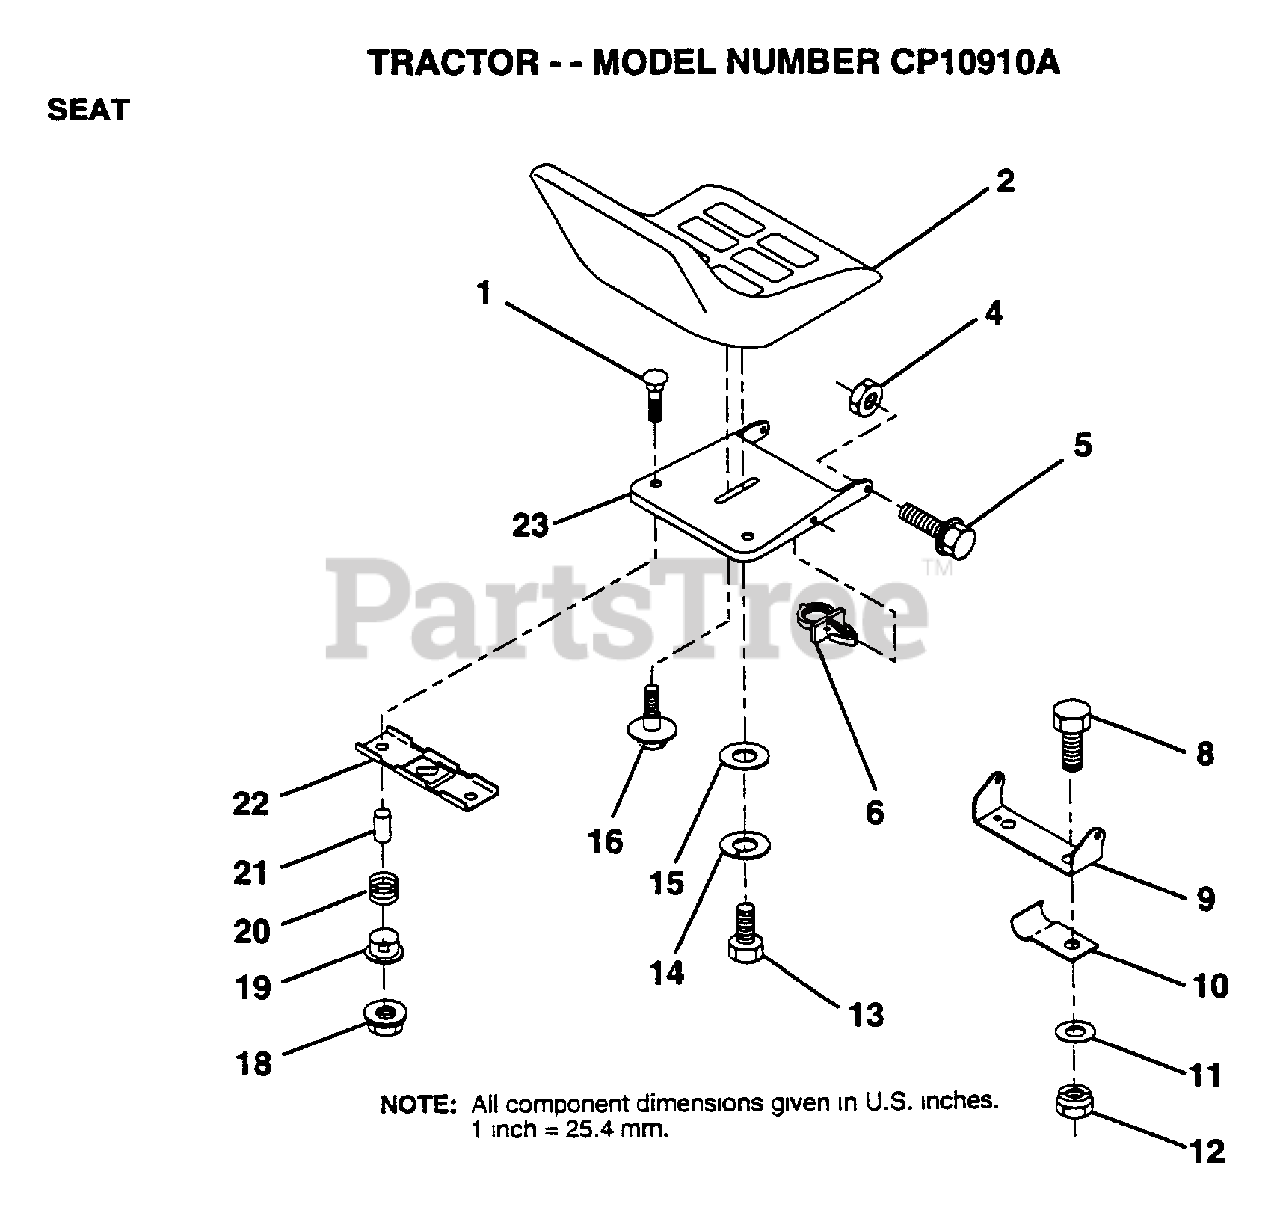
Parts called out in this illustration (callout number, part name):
4	NUT
5	BOLT.SHLD.5/16-18
6	CLIP.PUSH-IN.HING
8	BOLT
9	BRACKET PVT SEAT
10	"CLIP,INSULATOR"
11	WASHER
12	NUT
13	BOLT
14	LOCKWASHER
15	WASHER
16	"BOLT,SHOULDER"
19	BUSHING
20	SPRING
21	SPLIT SPACER
22	BRKT SWITCH
